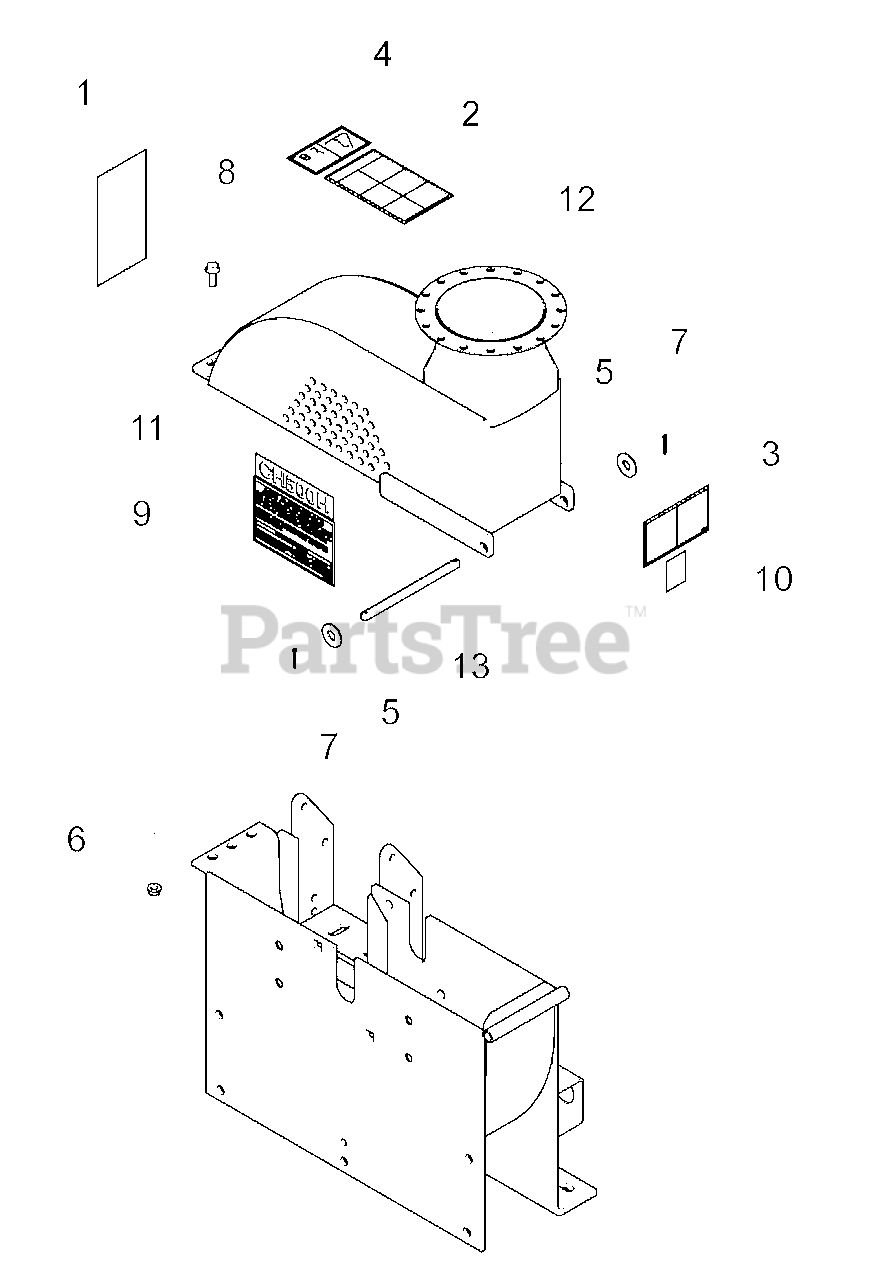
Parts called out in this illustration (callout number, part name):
1	DECAL, KNIFE ACCESS ISO
2	DECAL, OPERATING INSTRUCTIONS ISO
3	DECAL, DISCHARGE ISO
4	DECAL, MAINTENANCE ISO
5	WASHER, 1/2 FLAT CMS F1 5ANS
6	NUT, 3/8-16 SERRATED FLANGE
7	PIN, 1/8 X 1.00 ZP COTTER
8	BOLT, 3/8-16 X 1 SERRATED FLANGE GR5
9	DECAL, FLOW RATE HYDRAULIC
10	DECAL, ECHO BEARCAT QR CODE
11	DECAL, MODEL CH500H
12	WELDMENT, TOP CHIPPER HOUSING
13	SHAFT, CHIPPER TOP PIVOT
